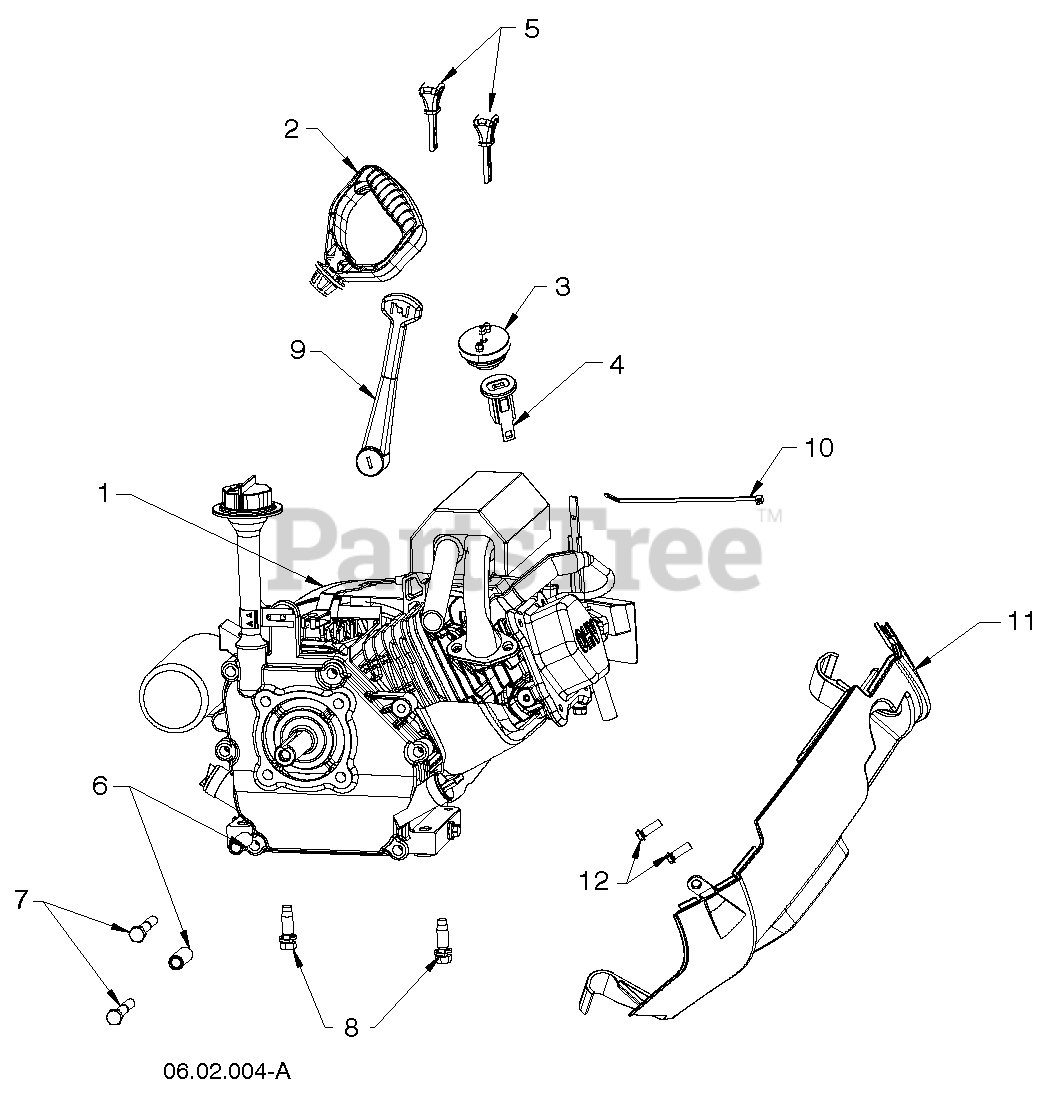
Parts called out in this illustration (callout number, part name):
1	ENGINE.LCT.208CC.E/S.SINGLE.ST
2	RP HANDLE.STARTER
3	RP BULB.PRIMER
4	KEY HOUSING
5	KEY SET(2 KEYS) SKSN0407.1
6	SPACER.ENGINE
7	SCREW. 5/16-24 X 2.00"HHCS
8	BOLT 3/8-16X1-1/8
9	LEVER.CHOKE
11	COVER REAR.LOWER.SSST.BLACK
12	SCREW.HX.13X.750
